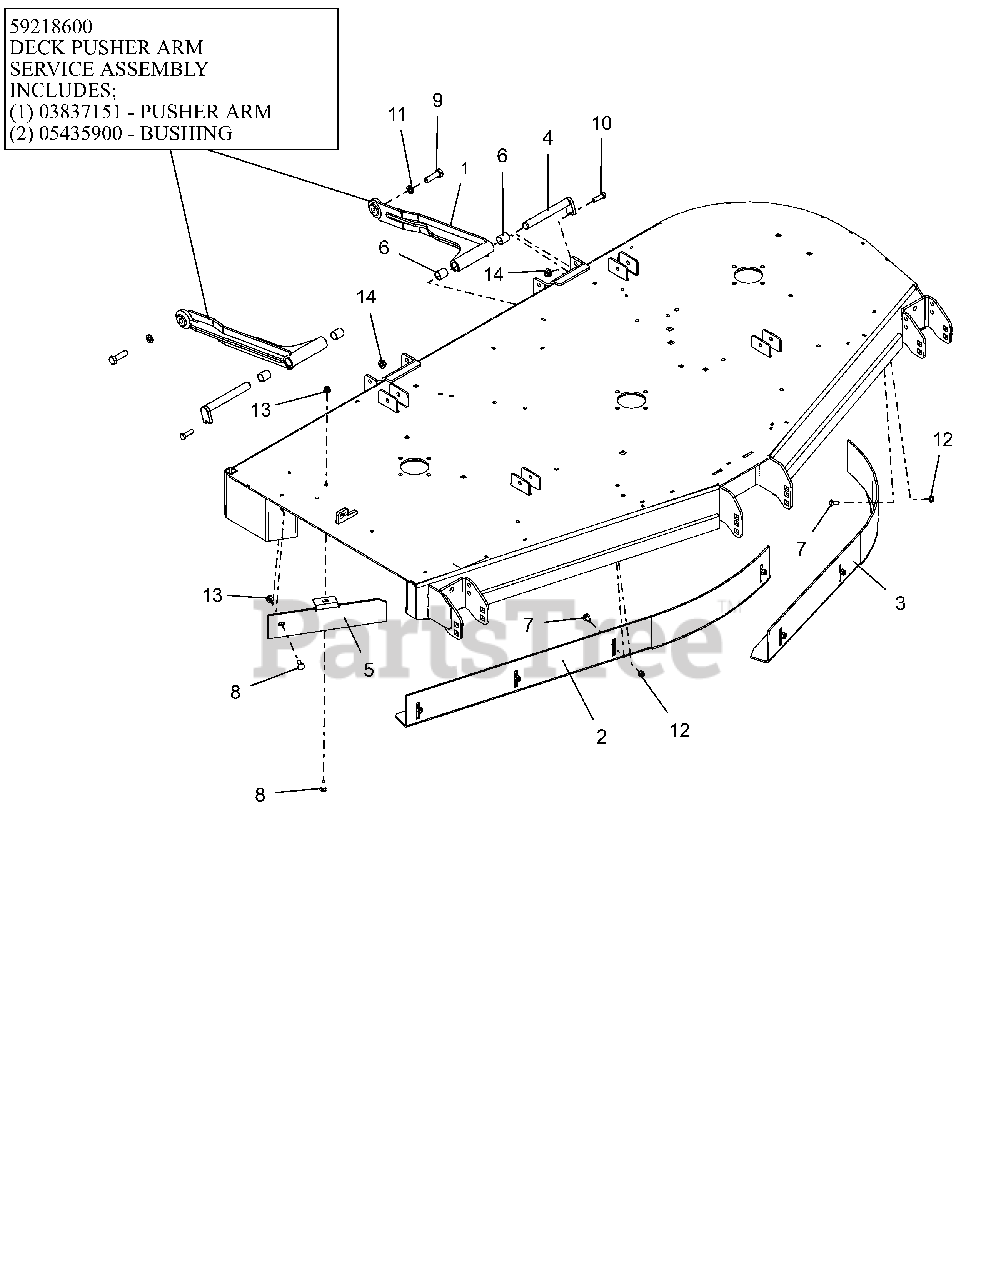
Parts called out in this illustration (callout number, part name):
1	DECK STABILIZER ARM - BLACK
1	DECK STABILIZER ARM W/BUSHINGS
1	BRG, .750 X .875 X 1.000
2	72" RH VACUUM BAFFLE WLDMT-RED
3	72" LH VACCUM BAFFLE WLDMT-RED
4	PIN, MOWER MTG
5	72" DISCHARGE BAFFLE - RED
6	BRG, .750 X .875 X 1.000
7	@BLT-RDHDSQNK .31-18X.75 G5YZ
8	@BLT-RDHDSQNK .31-18X1.00 G5YZ
9	BLT-HEX .50-13X1.75 GR5EP80 YZ
10	@BLT-HEX .38-16X1.25 GR5 YWZC
11	@WSHR-LK .50X.125 REG YWZC
12	@NUT-LK-NYL .312-18 YWZC
13	@NUT-LK-NYL-FLG .31-18 YWZC
14	@NUT-LK-NYL-FLG .38-16 YWZC
